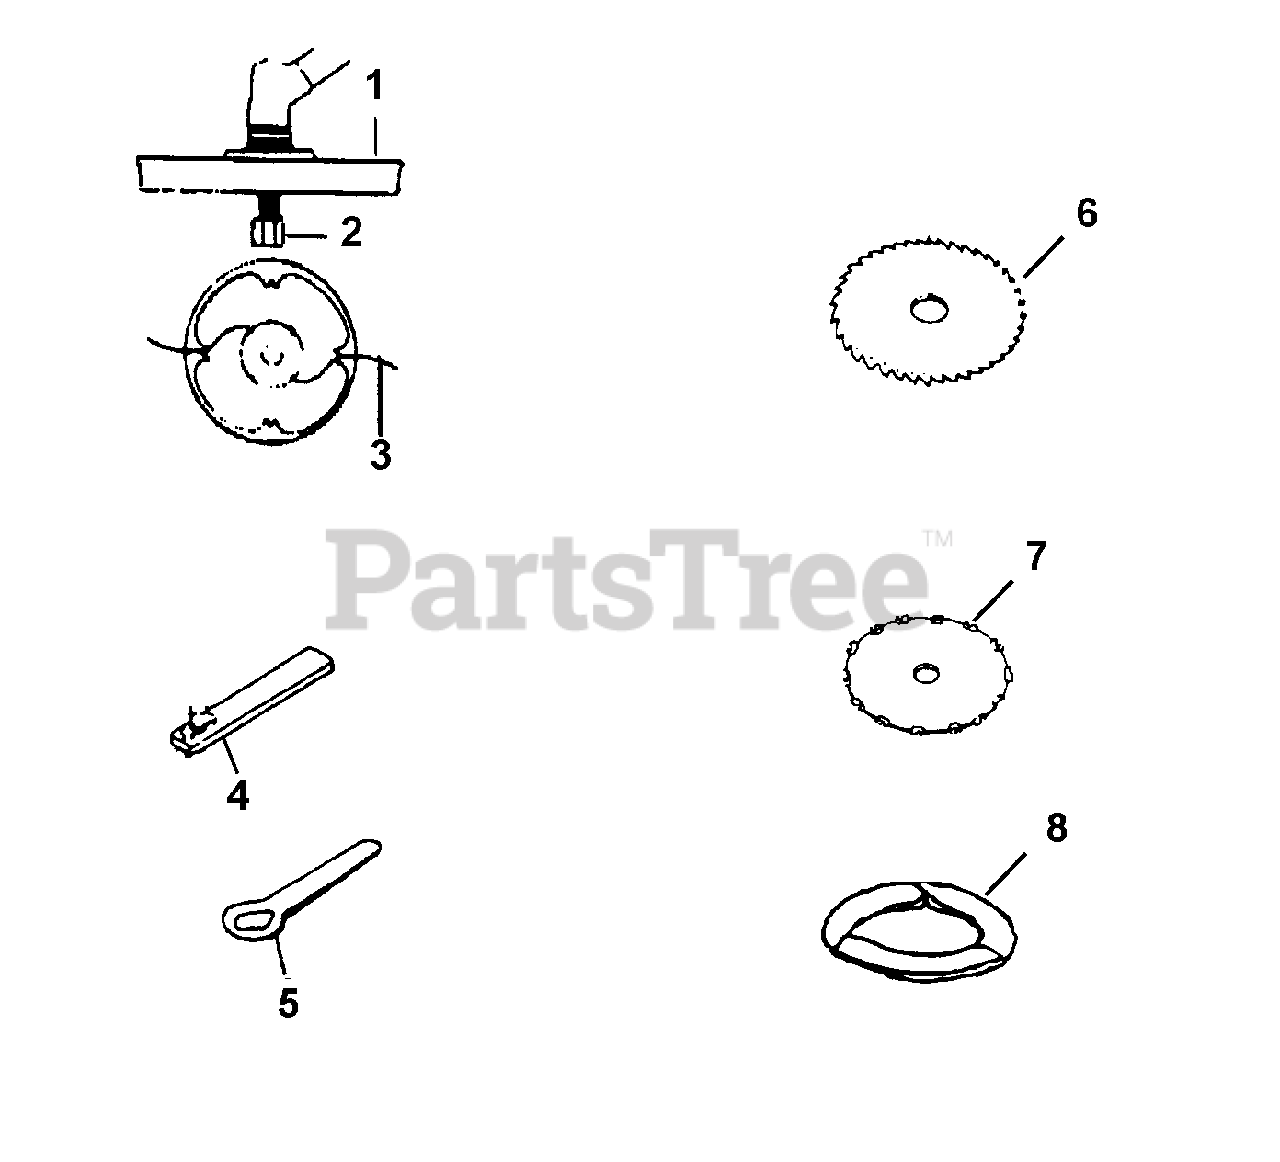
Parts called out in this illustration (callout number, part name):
1	Fixed Line Head
2	Arbor Bolt
3	Green Line .105 X 20"
4	Rotor Puller
5	Flywheel Holder
6	Saw Blade
7	XRT Blade
8	Cover, Blade
